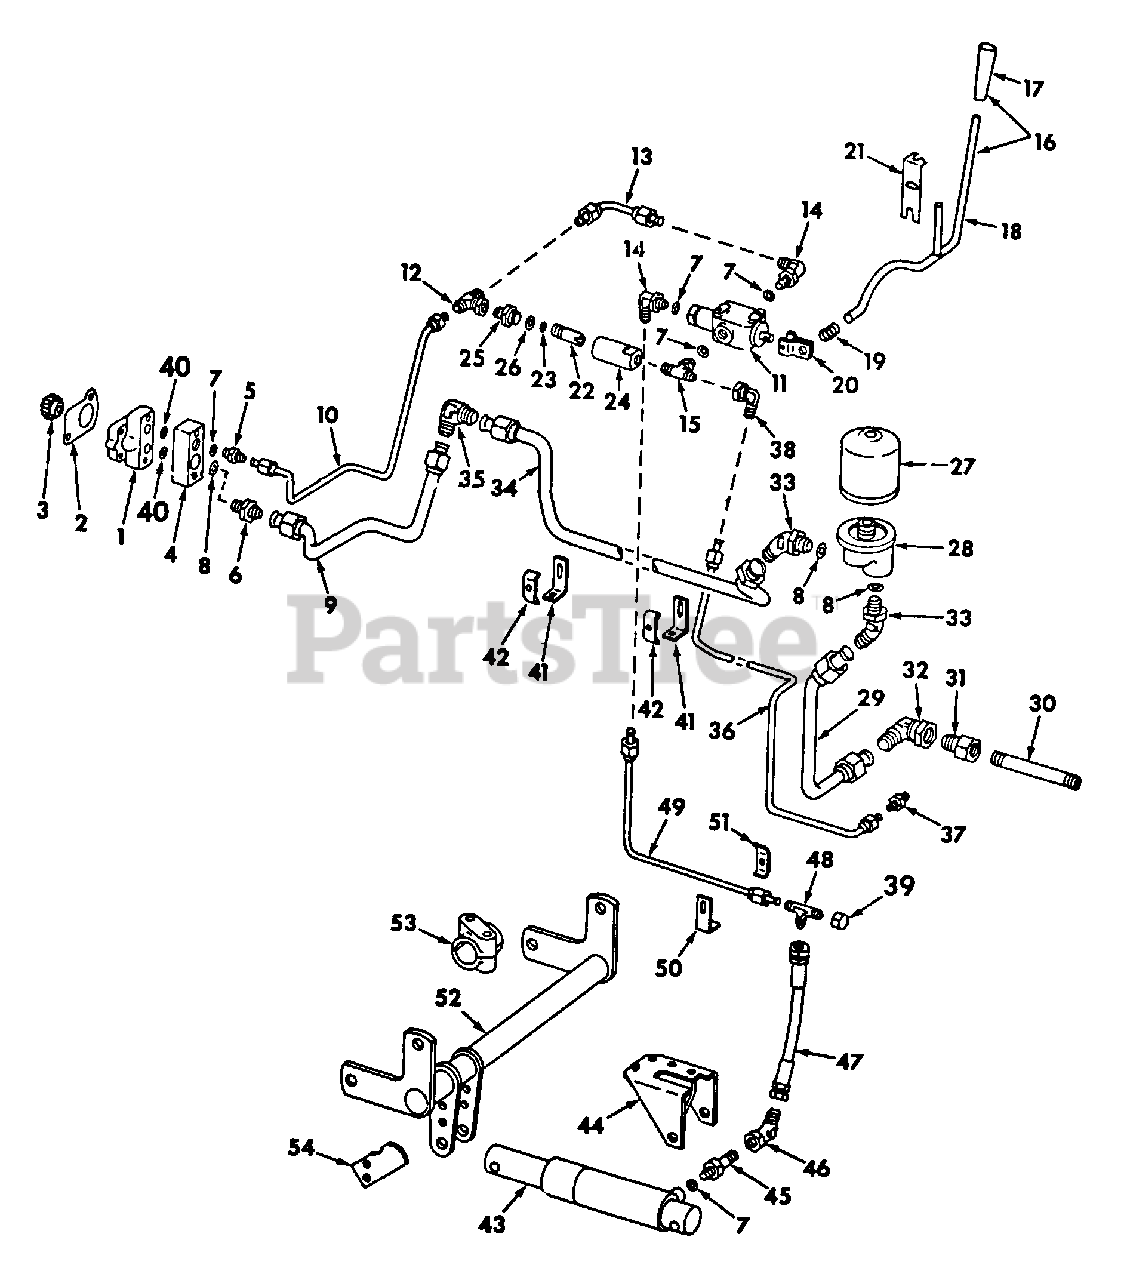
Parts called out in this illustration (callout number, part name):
1	PUMP ASSY, HYDRAULIC - WARNER MOTIVE
2	GASKET, PUMP
3	GEAR, PUMP DRIVE - 10T
4	FLANGE, HYD PUMP
5	UNION, 9/16-18 C-Z 37 DEG HYD FLARED TUBE SHORT SWIVEL
6	UNION, 1-1/16-12 C-Z 37 DEG HYD FLARED TUBE SHORT SWIVEL
7	O-RING, 3/8 OD TUBE
8	O-RING, 3/4 OD TUBE
9	TUBE ASSY, SUCTION SHORT
10	TUBE ASSY, PRESSURE LONG
11	VALVE ASSY, SINGLE ACTING CONTROL
12	TEE, 9/16-18 37 DEG HYD FLARED TUBE 90 DEG SWIVEL
13	TUBE ASSY, PRESSURE SHORT
14	ELBOW, 9/16-18 37 DEG HYD FLARED TUBE ADJ STR THD 90 DEG
15	TEE, 9/16-18 37 DEG HYD FLARED TUBE ADJ STR THD
16	HANDLE W/GRIP, VALVE
19	SPRING, VALVE HANDLE
20	BAR ASSY, HYD VALVE OPERATING
21	LOCATOR, VALVE HANDLE
22	VALVE ASSY, SAFETY 1500 PSI
23	O-RING, 3/8 X 9/16 X 3/32 SAFETY VALVE
24	HOUSING, SAFETY VALVE
25	CONNECTOR, HYD TUBE REDUCING
26	O-RING, 3/4 X 15/16 X 3/32
27	FILTER ASSY, HYD OIL-SPIN-ON
28	BASE, HYD OIL FILTER
29	TUBE ASSY, HYD FILTER SUCTION
30	NIPPLE, 1/2-14 X 6 PIPE
31	CONNECTOR, 3/4-14 37 DEG HYD FLARED TUBE INT PIPE THD
32	ELBOW, 1-1/16-12 37 DEG HYD FLARED TUBE 90 DEG SWIVEL
33	ELBOW, 1-1/16 37 DEG HYD FLARED TUBE 45 DEG ADJ
34	TUBE ASSY, SUCTION LONG
35	ELBOW, 1-1/16-12 37 DEG HYD FLARED TUBE 90 DEG UNION
36	TUBE ASSY, RETURN
37	CONNECTOR, 9/16-18 37 DEG HYD FLARED TUBE
38	ELBOW, 9/16-18 37 DEG HYD FLARED TUBE 90 DEG SWIVEL
39	CAP, 9/16-18 37 DEG HYD FLARED TUBE
40	O-RING, 5/8 X 13/16 x 3/32 - HYD PUMP FLANGE
41	SUPPORT, TUBE CLAMP
42	CLAMP, HYD TUBES
43	CYLINDER ASSY, HYD 1-3/4 X 5
44	BRACKET ASSY, CYL MTG
45	UNION, 9/16-18 37 DEG HYD FLARED TUBE LONG
46	ELBOW, 9/16-18 37 DEG HYD FLARED TUBE 45 DEG SWIVEL
47	HOSE ASSY, HYDRAULIC
48	TEE, 9/16-18 37 DEG HYD FLARED TUBE THREE WAY
49	TUBE ASSY, HYDRAULIC CYLINDER
50	SUPPORT, TUBE CLAMP
51	CLAMP, HYD TUBES
52	ROCKSHAFT ASSY
53	BEARING ASSY, ROCKSHAFT
54	BAR, ROCKSHAFT STOP
